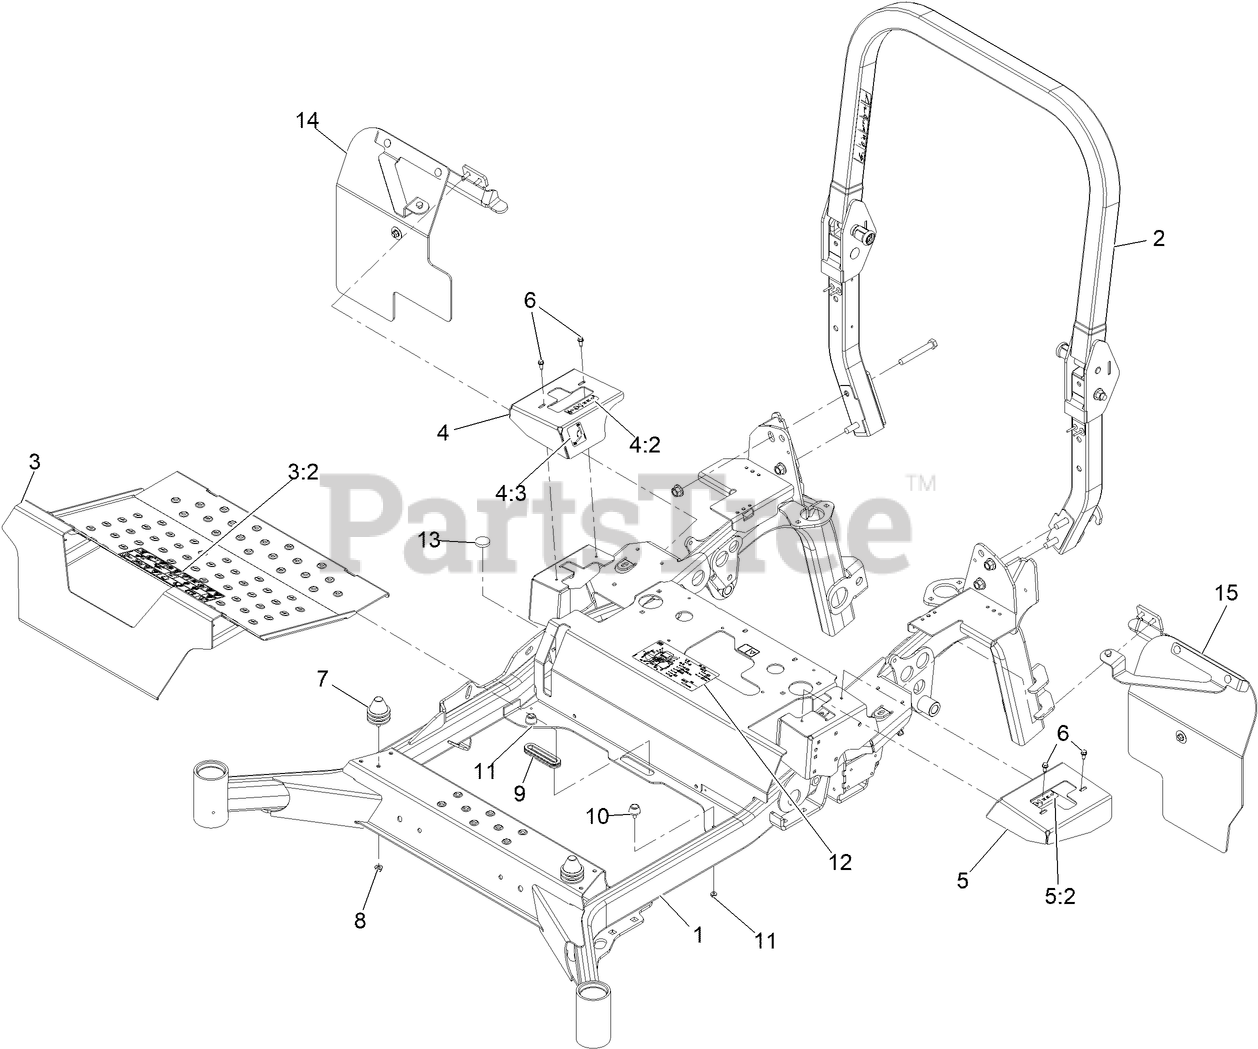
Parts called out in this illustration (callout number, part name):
1	MAINFRAME ASM, WD
2	ROPS ASM
3	PAN-FLOOR
3:2	DECAL-DANGER
4	COVER-MOTION CONTROL, RH
4:2	DECAL-CONTROL, MOTION
4:3	DECAL-PARK BRAKE, CE
5	COVER-MOTION CONTROL, LH
5:2	DECAL-CONTROL, MOTION
6	SCREW-HWH
7	ISOLATOR
8	NUT-HF, NI
9	GROMMET-RUBBER
10	BUMPER-RUBBER
12	DECAL-SERVICE AID
13	BUMPER-PUSH-IN, RUBBER
14	ASM, RH Mud Flap
15	ASM, LH Mud Flap
